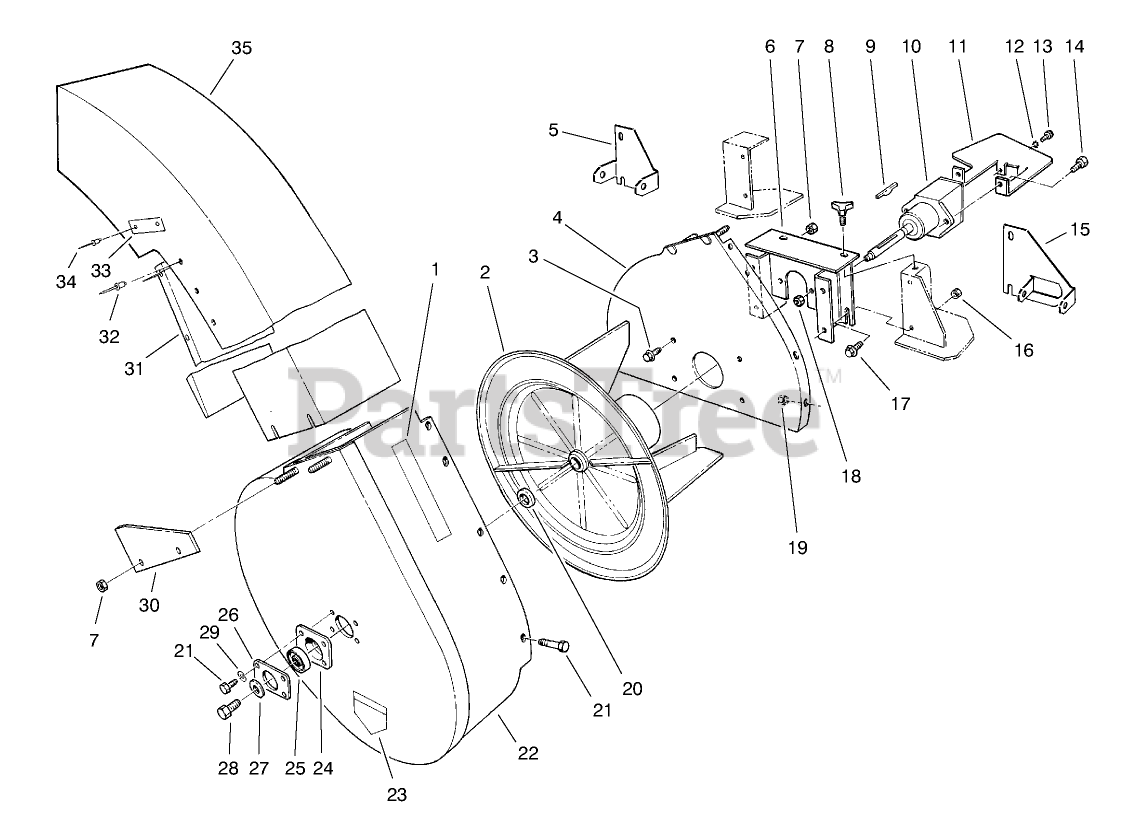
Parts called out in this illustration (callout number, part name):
1	DECAL
2	Impeller
3	SCREW-HHF
4	Plate-Mounting
5	Bracket-Pivot LH
6	Mount-Blower
7	NUT-LOCK, NI
10	Asm-Gear Box
11	Cover-Gear Box
12	WASHER-LOCK, EXT
14	SCREW-HH
15	Bracket-Pivot RH
16	NUT-JAM
17	SCREW-HHF
18	NUT-LOCK, NI
19	NUT-LOCK, NI
20	SPACER-BEARING
21	SCREW-HH
22	Blower Housing (Incl. Ref. #1 & 23)
23	DECAL-DANGER
24	CUP-BEARING
25	BEARING-BALL
26	Cover-Plate
27	SPACER
28	SCREW-HH, LOCK
29	WASHER-LOCK
30	Bracket
31	Deflector-Chute
33	PLATE - WARNING
34	RIVET-POP
35	Chute Assembly (Incl. Ref. #31-34)
